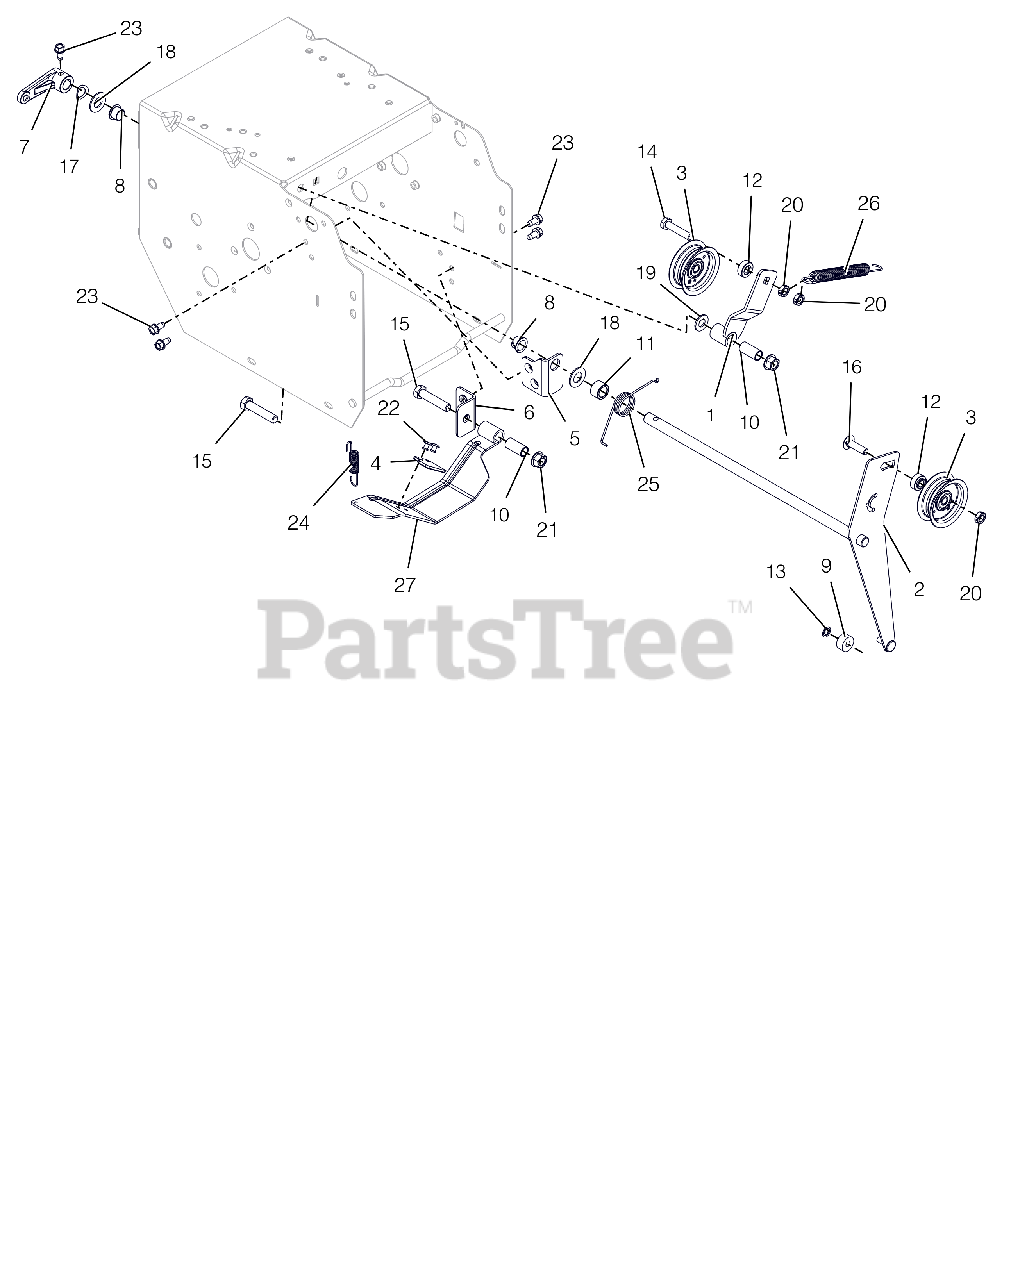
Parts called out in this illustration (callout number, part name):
1	ARM, TRACTION IDLER
2	WELDMENT, ATTACHMENT IDLER ARM
3	IDLER, FLAT - 2.00"
4	PAD, BRAKE
5	BRACKET, MOUNT - IDLER ARM
6	BRACKET, MOUNT - BRAKE
7	ARM, CLUTCH - ATTACHMENT
8	BUSHING, POLYLINER-.50 SPLIT
9	BSHG,SLV .265 X .625 X .375
10	BSHG-SLV .385X.500X1.045
11	BSHG-SLV .510X.751X.475
12	SPCR, BRG .315X.500X.358X.281
13	RG-RTNG-EXT .250X.010
14	@BLT-HEX .31-18X1.50 GR5 YWZC
15	@BLT-HEX .38-16X1.75 GR5 YWZC
16	BLT-RDHDSQSHNK.31-18X1.13 G5YZ
17	WSHR-WAVE .50X.75X.015 .13FRHT
18	WSHR-FL-STL.531X1.00X.063 YWZC
19	@WSHR-FL-STL.406X.812X.065 YWZ
20	@NUT-LK-CTR-JAM .31-18 YWZC
21	@NUT-LK-TOP-FLG .38-16 YWZC
22	RVT-POP .187 YZ
23	SCR-TAP .25-20X.50 HWH TR YWZ
24	SPRING-EXT .437 X .438 X 2.64
25	SG-TORS .075 X .955
26	SPRING, SWIVEL HOOK EXTENSION
27	BRAKE ARM W/PAD
